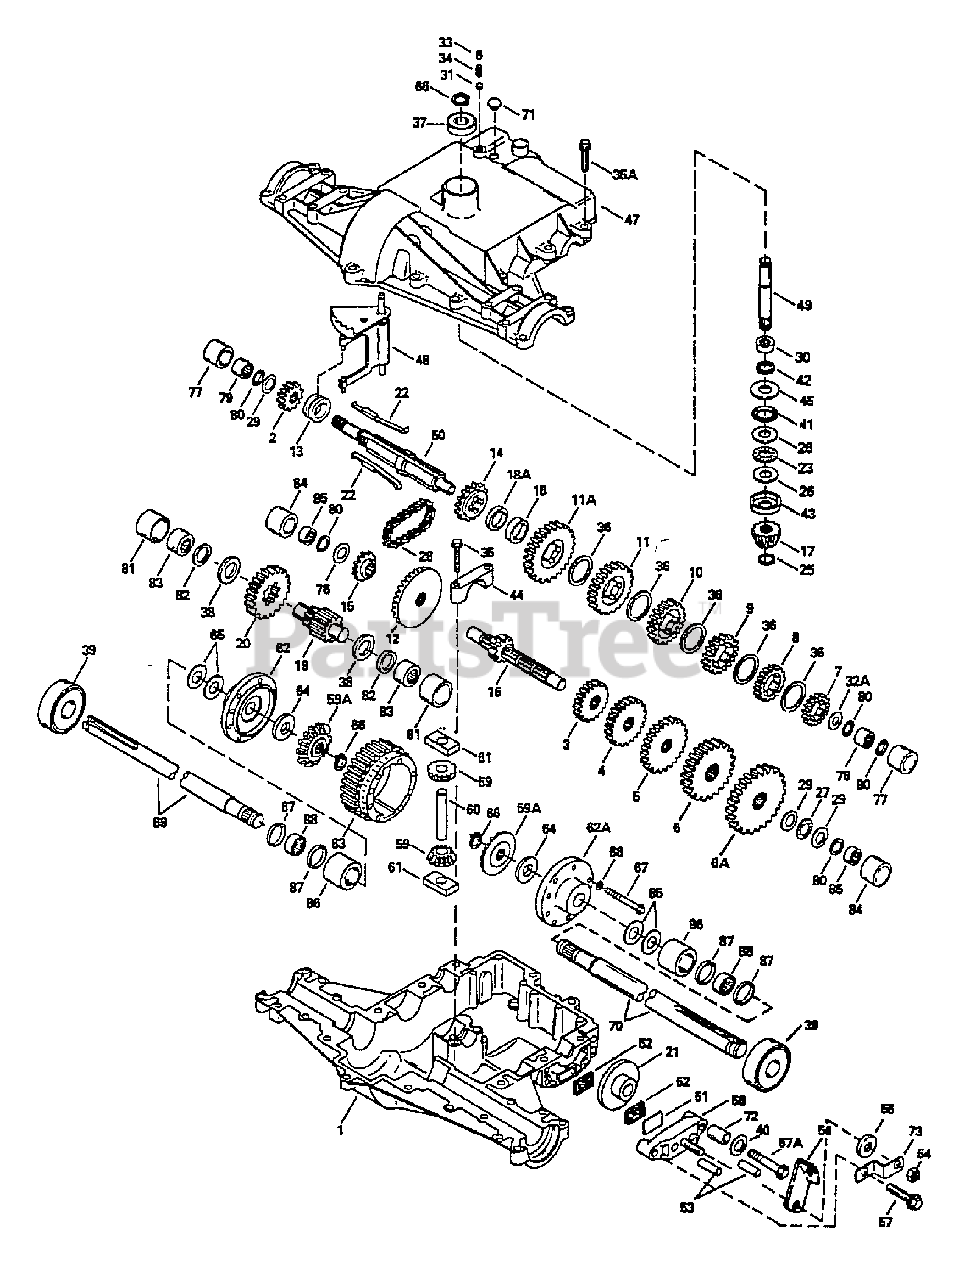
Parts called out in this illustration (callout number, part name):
1	Case, Transaxle
2	Gear, Spur 15 Teeth
3	Gear, Spur 12 Teeth
4	Gear, Spur 18 Teeth
5	Gear, Spur 25 Teeth
6	Gear, Spur 28 Teeth
6A	Gear, Spur 31 Teeth
7	Gear, Spur 19 Teeth
8	Gear, Spur 21 Teeth
9	Gear, Spur 25 Teeth
10	Gear, Spur 32 Teeth
11	Gear, Spur 37 Teeth
11A	Gear, Spur 41 Teeth
12	Gear, Bevel 33 Teeth
13	Collar, Shift
14	Sprocket 18 Teeth
15	Sprocket 9 Teeth
16	Shaft, Counter (with 9 Tooth Gear)
17	Bevel Pinion, Input 13 Teeth
18	Spacer, Neutral .350/.340 Thick
18A	Spacer, Neutral .276/.268 Thick
19	Shaft, Output 9 Teeth
20	Gear, Output 35 Teeth
21	Disk, Brake
23	Bearing, Thrust
25	Ring, Retaining
26	Washer, Thrust
27	Bearing, Thrust
28	Chain, Roller (Number 41 Chain, 24 Links)
29	Washer, Thrust
30	Bearing, Needle
31	Ball, Steel
32A	Washer, Thrust
33	Screw, Set 3/8-16 x 3/8
35	Screw, Flanged Hex Head, Thread Forming 1/4-20 x 1-1/4
35A	Screw, Hex Head, Thread Forming 5/16-18 x 1-1/4
36	Washer, Thrust
37	Bearing, Ball
38	Washer, Thrust
39	Bearing, Ball
40	Washer, Flat
41	"O" Ring
42	Seal, Oil
43	Washer, Cupped
44	Cap, Bearing
45	Washer, Flat
47	Cover, Transaxle
48	Rod and Fork Assembly, Shift
49	Shaft, Input
50	Shaft, Brake, 4 Keyed
51	Plate, Brake Pad
52	Pad, Brake
53	Pin, Dowel
54	Locknut 5/16-24
55	Washer, Flat
56	Lever, Brake
57	Screw, Flanged Hex Head, Thread Forming 1/4-20 x 1-1/4
57A	Screw, Flanged Hex Head, Thread Forming 1/4-20 x 2-1/4
58	Holder, Brake Pad
59	Pinion, Differential Bevel
59A	Gear, Bevel
60	Pin, Drive
61	Block, Drive
62	Carrier, Differential, Threaded Holes
62A	Carrier, Differential
63	Gear, Ring 31 Teeth
65	Washer, Thrust
66	Ring, Snap
67	Screw, Hex Head 1/4-20 x 2-1/4
68	Washer, Lock 1/4
69	Axle 12-5/16"
70	Axle 16-3/16"
71	Plug, Hex Head 9/16-18 Thread
73	Bracket, Brake Lever
77	Sleeve, Stepped
78	Bearing, Needle
79	Bearing, Needle, Capped
80	"O" Ring
81	Sleeve, Stepped
82	Ring, Square Cut
83	Bearing, Needle, Capped
84	Sleeve, Stepped
85	Bearing, Needle, Capped
86	Sleeve, Stepped
87	Ring, Square Cut
88	Bearing, Needle
